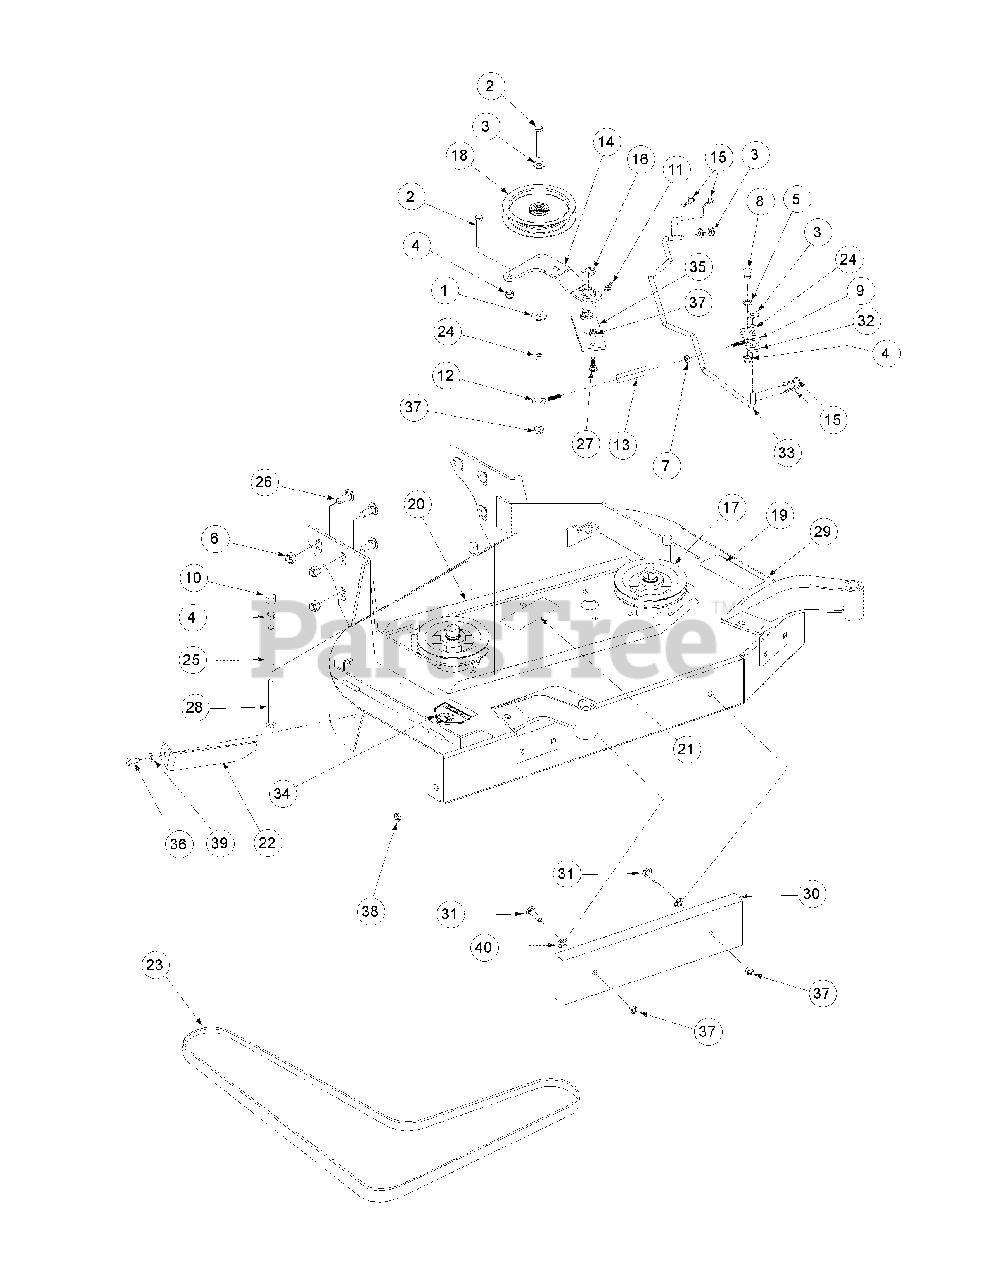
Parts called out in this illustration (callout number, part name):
1	Washer, 1.25 x .411 x .100
2	Hex Cap Screw, 3/8-16 x 2.75
3	Flat Washer, 3/8 Zinc
4	Lock Nut, Nylon Insert, 3/8-16
5	Shim Washer
6	Nut, Flange Lock, 1/2-13
7	Hex Nut, 5/16-18
8	Shoulder Bolt
9	Eye Bolt, Right Hand
10	Cap, Black Vinyl
11	Grease Fitting, 45°, 1/4-28
12	Eye Bolt, Left Hand
13	Turnbuckle
14	Idler Arm
15	Hair Pin, 3/8"-1/2"
16	E-Ring, Retainer
17	Pulley Deck
18	Idler Deck Take-up
19	Decal Rotating Blade
20	Deck Stiffener
21	Decal, Warning Shield Missing
23	Belt Drive
24	Turnbuckle, Sleeve
25	Spacer, Belt Guide
26	Carriage Bolt, 1/2-13 x 1-1/4
27	Carriage Bolt, 3/8-16 x 1.25
28	Carriage Bolt, 3/8-16 x 4.5
31	Carriage Bolt, 3/8-16 x 1-1/2
33	Rod Clutch Link
34	Decal, Danger Hands and Feet
35	Idler Base
36	Hex Cap Screw, 5/16-18 x .75
37	Hex Nut Flange Lock, 3/8-16
38	Nut, Hex Flange Lock, 5/16-18
39	Flat Washer, 5/16
40	Push Retainer
